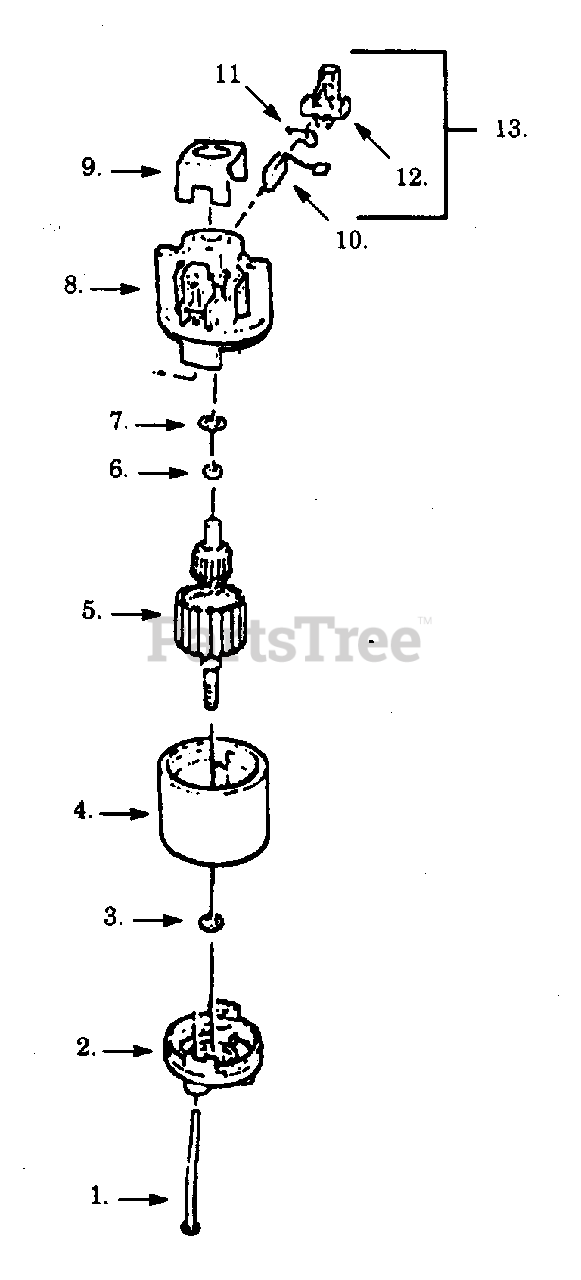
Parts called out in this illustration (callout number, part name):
2	Endbell Ass'y. (Drive)
4	Field Ass'y.
5	Armature Ass'y.
8	Endbell Ass'y. (Brush)
9	Insulator
10	Carbon Brush
11	Brush Spring
12	Brush Holder
13	Brush Kit (Inc. 10,11,12)
